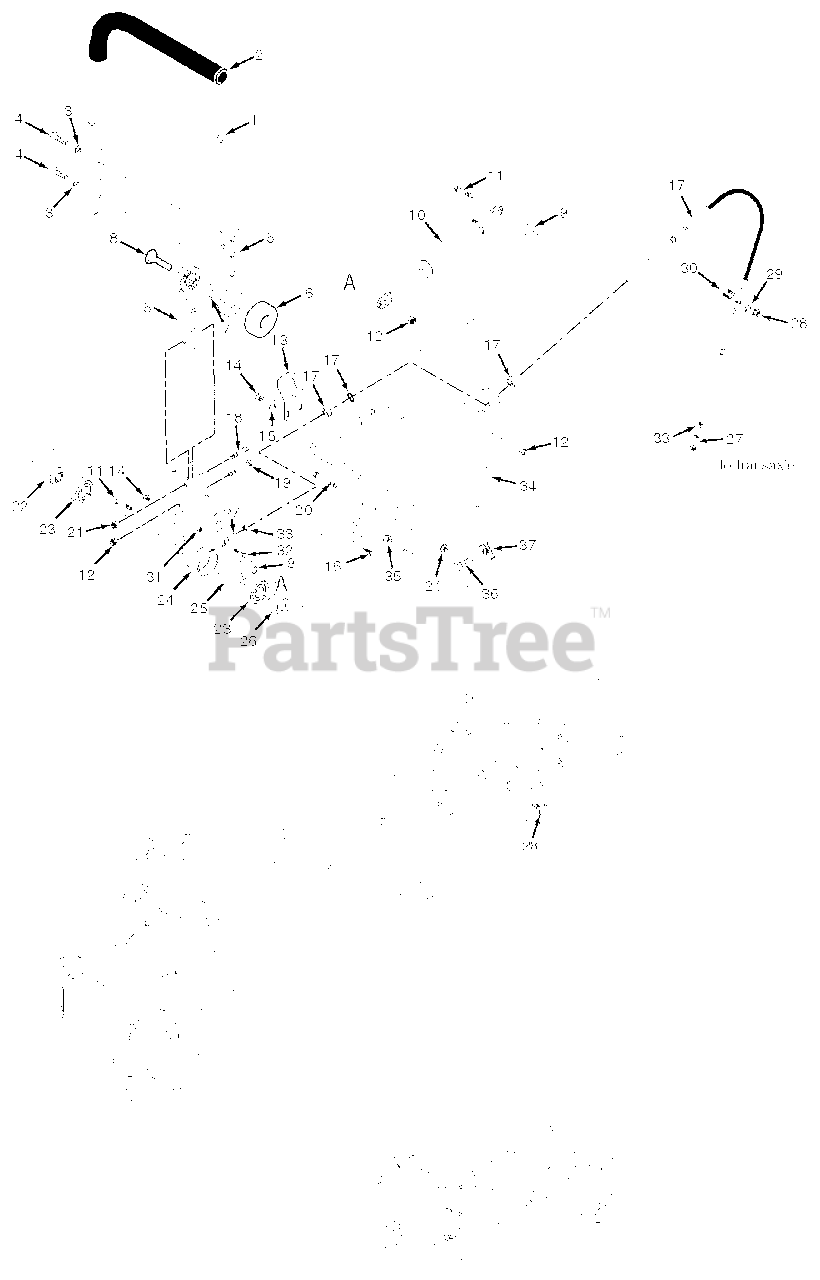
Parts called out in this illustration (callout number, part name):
1	Handle Bar w/Grip, LH
1	Handle Bar w/Grip, RH
2	Grip, Control Handle
3	Lockwasher, 5/16-" Spring
4	Bolt, Hex Head 5/16-18 x 1'
5	Pivot, Control Lever
6	Knob, Control Handle
7	Spacer, Rubber
8	Bolt, Carriage 3/8-16 x 1-1/2"
9	Spacer
10	Damper
11	Bolt, Hex Head 5/16-18 x 2"
12	Nut, Elastic Stop 5/16-18
13	Bracket, Operator Presence Switch
14	Nut, Elastic Stop 1/4-20
15	Flatwasher, 1/4-.312 x .750 x .065
16	Bolt, Carriage 1/4-20 x 3/4"
17	Control Cable, Hydro
18	Bolt, Hex Head 5/16-18 x 2"
19	Bolt, Hex Head 5/16-18 x 2"
20	Bolt, Hex Head 3/8-16 x 6"
21	Nut, Elastic Stop 3/8-16
22	Spacer, Controls
23	Bearing
24	Pivot Weldment, Control Arm LH
24	Pivot Weldment, Control Arm RH
25	Spacer, Bearing
26	Spacer, Controls
27	Rod End, 1/4-28 RH Thread
28	Nut, Jam 5/16-24 UNF-2B
29	Lockwasher, 5/16" Spring
30	U-Bolt, 5/16-24
31	Spacer
32	Bolt, Hex Head 1/4-20 x 1-1/4"
33	Nut, Jam 1/4-28 UNF
34	Bracket Weldment, Control Lever RH w/Decal
34	Bracket Weldment, Control Lever LH w/Decal
35	Nut, Serrated Flange 5/16-18
36	Bolt, Hex Head 3/8-16 x 2" Special
37	U-Nut, 3/8-16
